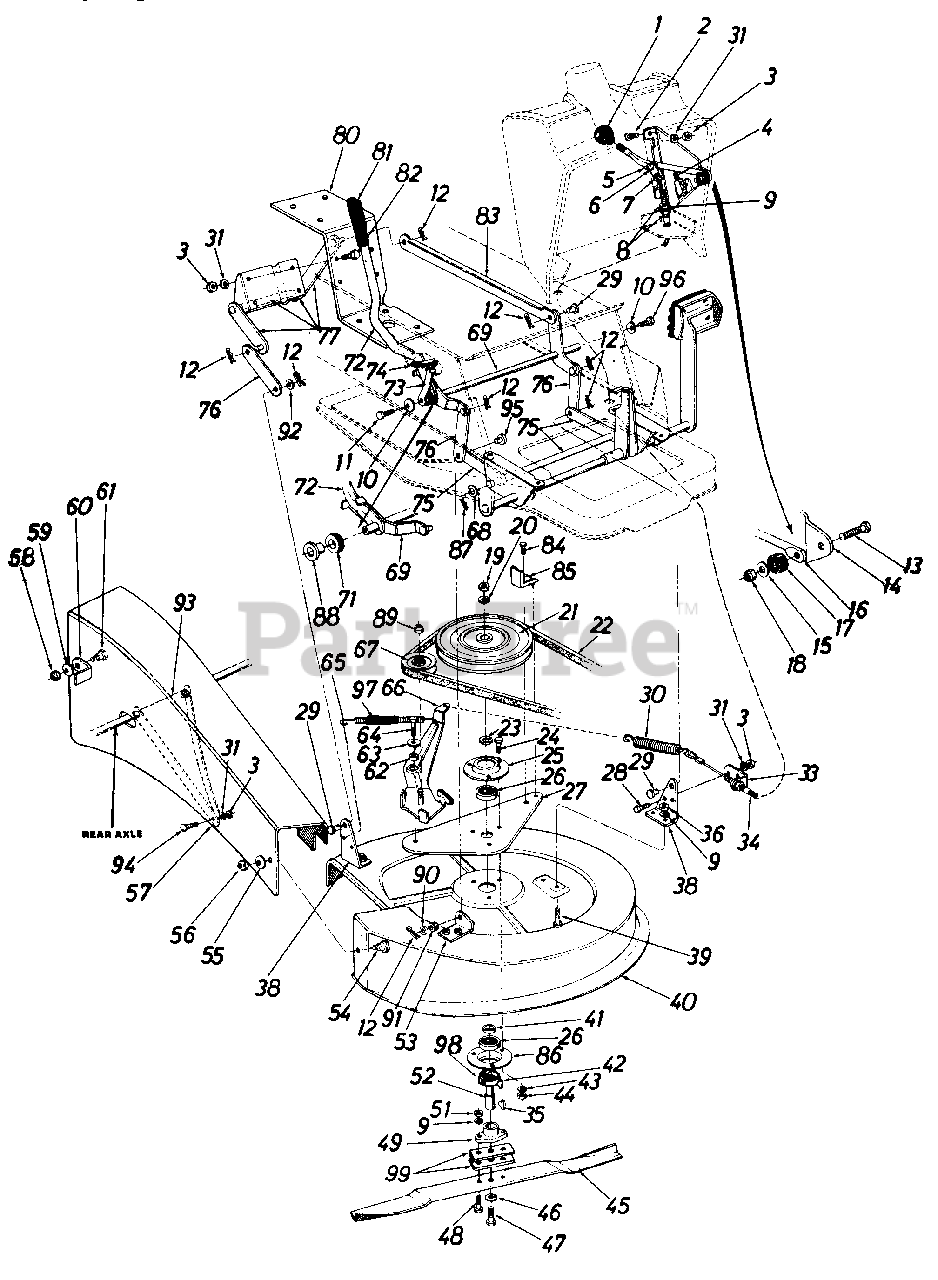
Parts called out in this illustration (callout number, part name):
1	Ball Knob
2	Truss Mach. Scr. 1/4-20 x .50" Lg.
3	Hex Nut 1/4-20 Thd.
4	Safety Switch
5	Weld Pin .25" Dia. x .62" Lg.
6	Push Cap .25" Dia.
7	Clevis
8	Hex Jam Nut 5/16-24 Thd.*
9	L-Wash. 5/16 I.D.
10	Bell-Wash. .40" I.D. x 1.11"
11	Hex Wash. Hd. Self-Tap Scr. 3/8-16 x 1.25" Lg.
12	Internal Cot-Pin 1/2" Dia.
13	Hex Bolt 1/4-20 x 1.25" Lg.
14	Deck Clutch Control Brkt.
15	Fl-Wash. .28" I.D. x .75" O.D. x .063
16	Blade Clutch Lever
17	Rubber Washer
18	Hex Cent. L-Nut 1/4-20 Thd.
19	Hex Nut 5/8-11 Thd.*
20	L-Wash. 5/8" I.D.
21	Deck Pulley
22	"V"-Belt
23	Spacer
24	Hex Sems Bolt 5/16-18 x 1.0" Lg.*
25	Bearing Housing
26	Ball Brg. .787" I.D. x 1.85" O.D.
27	Deck Belt Guard Plate
28	Hex Sems Bolt 1/4-20 x .75"
29	Lift Brkt. Pin Special
30	Extension Spring .88" O.D. x 4" Lg.
31	L-Wash. 1/4" I.D.
33	Cable Bracket
34	Clutch Control Cable 26.88" Lg.
35	#6 Hi-Pro Key 5/32 x 5/8" Dia.
36	Hex Nut 5/16-18 Thd.
38	Deck Bracket
39	Carriage Bolt 5/1 6-18 x .75" *
40	26" Deck Ass'y. Comp.
41	Spacer .836" I.D. x 1.01" O.D. x.32" Lg.
42	#61 Hi-Pro Key 3/16 x 518" Dia.
43	L-Wash. 5/16 I.D.
44	Hex Nut 5/16-18 Thd.
45	26" Blade
46	L-Wash. 3/8" I.D. H.D.
47	Hex Bolt 3/8-24 x 2.0" Lg. H.T.
48	Hex Bolt 5/16-24 x 1.5" Lg. H.T.-Special
49	Blade Adapter
51	Hex Nut 5/16-24 Thd.
52	Blade Spindle
53	Deck Bracket
54	Shld. Scr. .5" Dia. x .17" Lg.
55	Fl-Wash. 385" I.D. x .88" O.D.
56	Hex Cent. L-Nut 3/8-16 Thd.
57	Chute Ass'y.
58	Hex Ins. L-Nut 5/16-18 Thd.
59	Bell-Wsh. .345" I.D. x .88"
60	Chute Pivot Brkt.
61	Shld. Bolt .437 I.D. x .18" Lg.
62	Spacer .315" I.D. x .75" O.D. x .37 Lg.
63	Fl-Wash. .344" I.D. x 1.12" O.D. x .12
64	Hex Bolt 5/16-18 x 1.0" Lg.
65	Extension Spring
66	Deck Idler Brkt. Ass'y.
67	V-Idler Pulley
68	Fl-Wash. .63" I.D. x .93" O.D. x .06"
69	Lift Handle Shaft Ass'y.
71	Rubber Wash.
72	Lift Handle
73	Lift Handle Stop
74	Height Adj. Knob
75	Lift Arm Shaft Ass'y.
76	Deck Link
77	Lift Pivot Brkt. Ass'y.
80	Seat Support Ass'y.
81	Grip
82	Hex Sems Bolt 1/4-20 x 1.0" Lg.
83	Connecting Link
84	Hex Wash. Hd. Self-Tap Scr. 5/16-24 x .75" Lg.
85	Belt Keeper Ass'y.
86	Open Bearing Hsg.
87	Cotter Pin 3/32" Dia. x 75"
88	Flange Brg. .62" I.D. x .87" O.D. x .63" Lg.
89	Hex Ins. L-Nut 3/8-24 Thd.
90	Fl-Wash. .53" I.D. x.94" O.D. x .050"
91	Rubber Wash. .531" I.D. x 1.0" O.D. x .120"
92	Fl-Wash. .531" I.D. x .93" O.D. x .090"
93	Chute Baffie
94	Carriage Bolt 1/4-20 x .50"
95	Clevis Pin .50"
96	Self-Tap Scr. 3/16-16 x 1.0"
97	Shrink Tube
98	Bearing Shield
